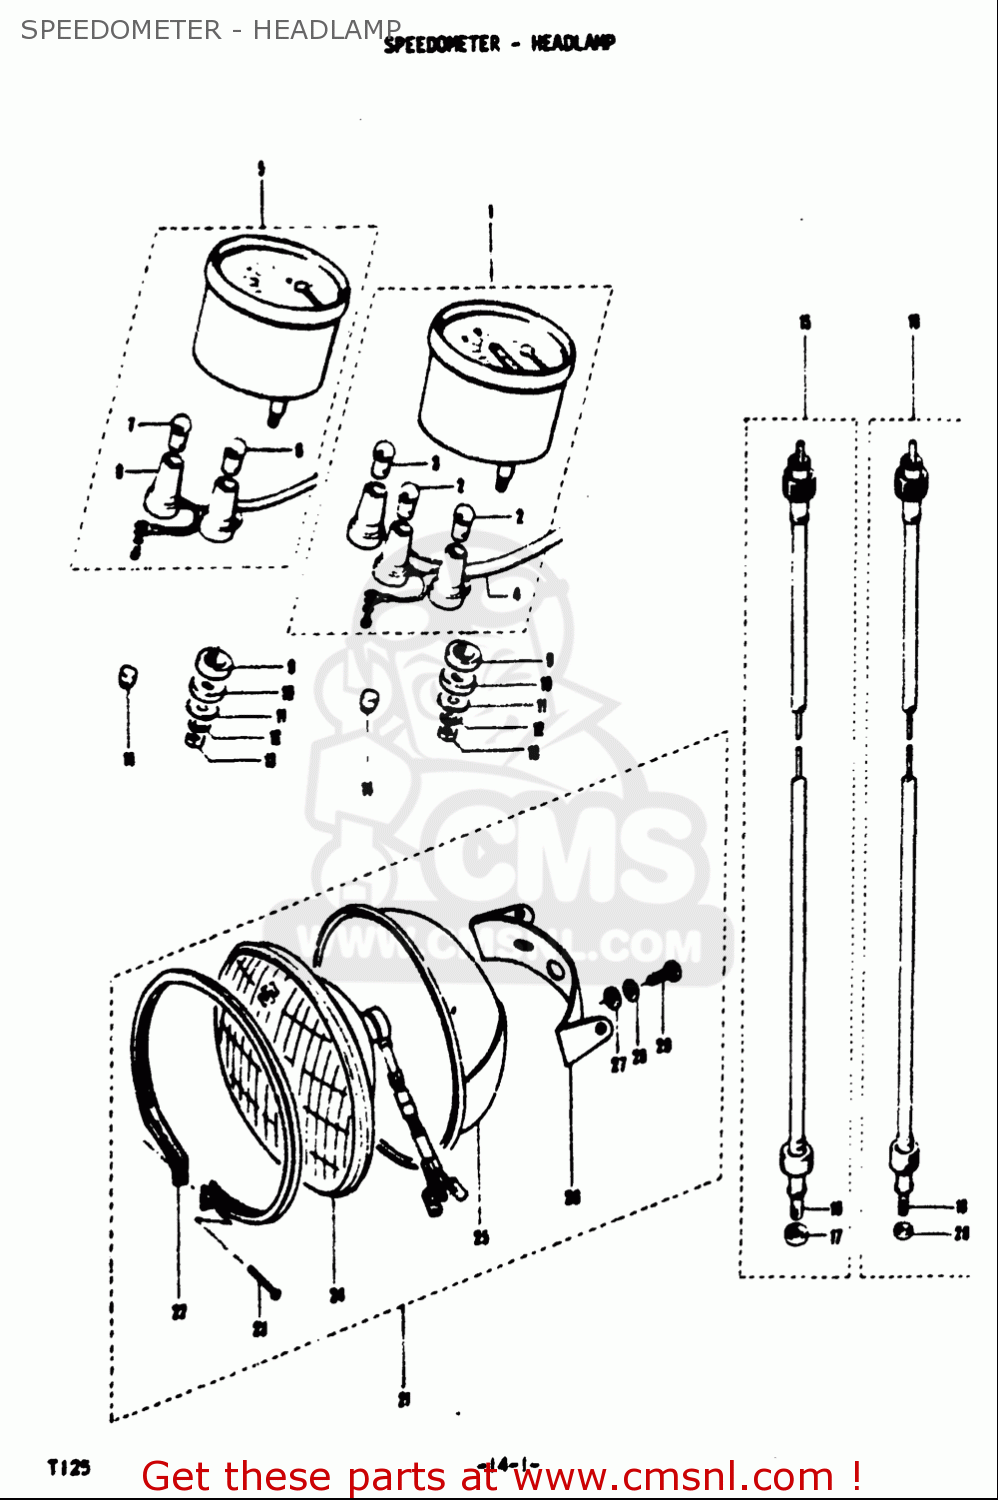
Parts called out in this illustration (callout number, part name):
2	BULB(6V/3W)
3	BULB(6V1.7W,STANLEY,A61A)
6	BULB(6V/3W)
7	BULB(6V1.7W,STANLEY,A61A)
9	CUSHION,METER
10	CUSHION
11	WASHER (5.5X18X1.6)
12	WASHER,LOCK
13	NUT
17	SEAL,OIL SPEEDOMETER CABLE
20	SEAL,OIL SPEEDOMETER CABLE
27	WASHER
28	WASHER,LOCK
